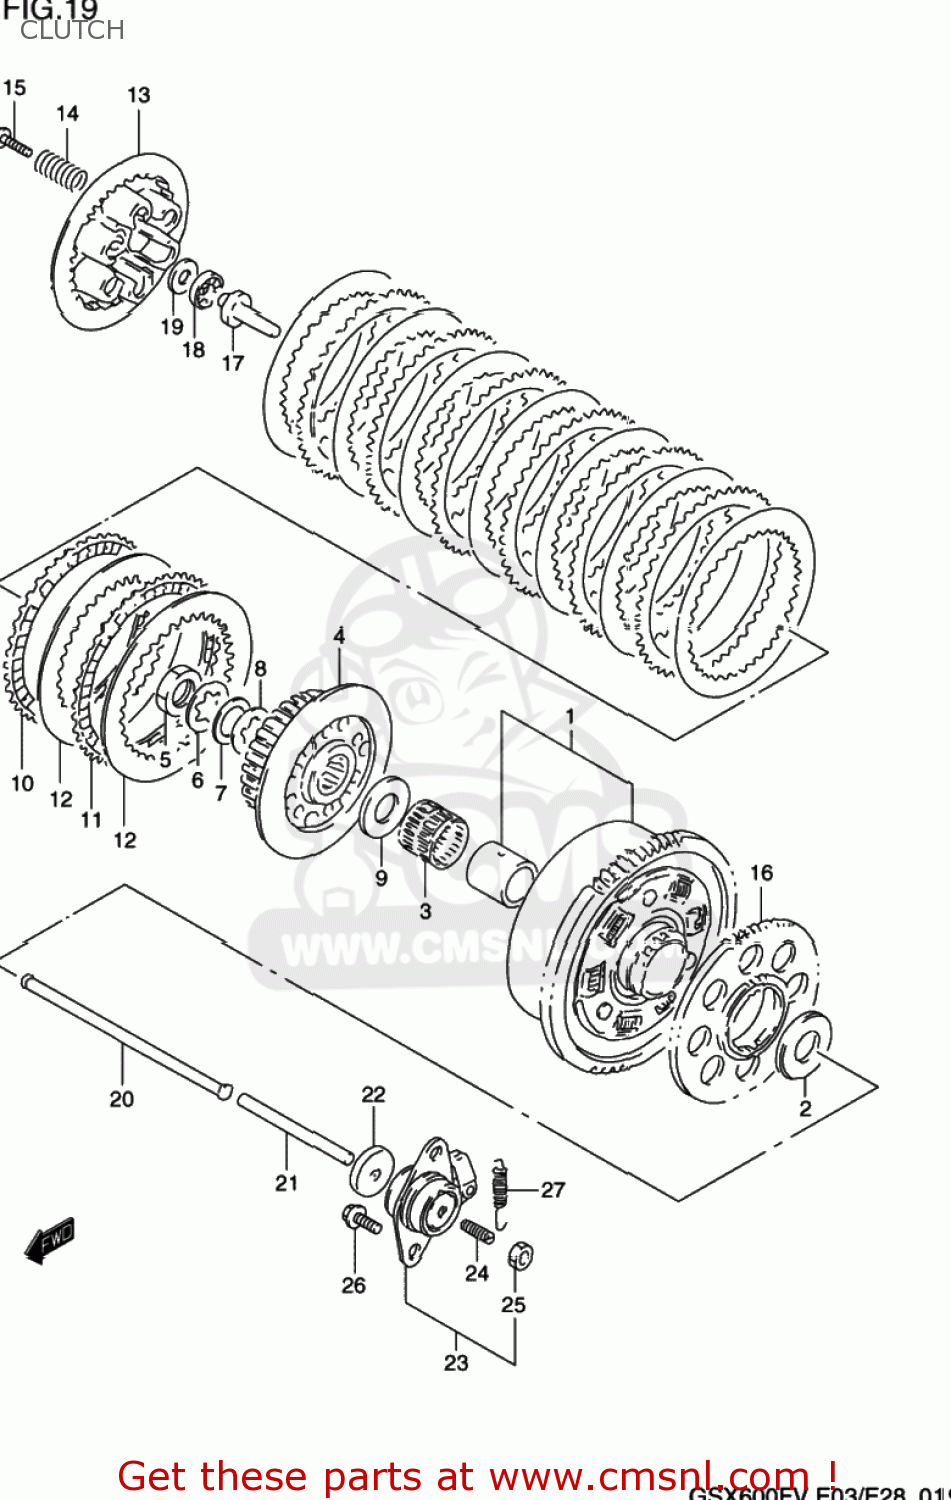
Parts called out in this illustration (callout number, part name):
1	GEAR ASSEMBLY,PRIMARY DRIVE
2	WASHER(25X54X2.5)
3	BEARING(35X40X35.8)
4	HUB,CLUTCH SLEEVE
5	NUT
6	WASHER,LOCK
7	WASHER
8	WASHER,LOCK
9	WASHER(25X50X2.5)
10	PLATE,CLUTCH DRIVE (NAS)
11	PLATE,CLUTCH DRIVE NO.2 (NAS)
12	PLATE,CLUTCH DRIVEN (NAS)
13	DISC,CLUTCH PRESSURE
14	SPRING
15	BOLT(6X25)
16	GEAR,GENERATOR DRIVE,N
17	PIECE,CLUTCH PUSH
18	BEARING(15X28X2)
19	WASHER(15.5X28X1)
20	ROD,CLUTCH PUSH,R
21	ROD,CLUTCH PUSH,L
22	SEAL,OIL(6X34X5.5)
23	SCREW ASSY,CLUTCH RELEASE
24	SCREW(6X25)
25	NUT
26	BOLT
27	SPRING
